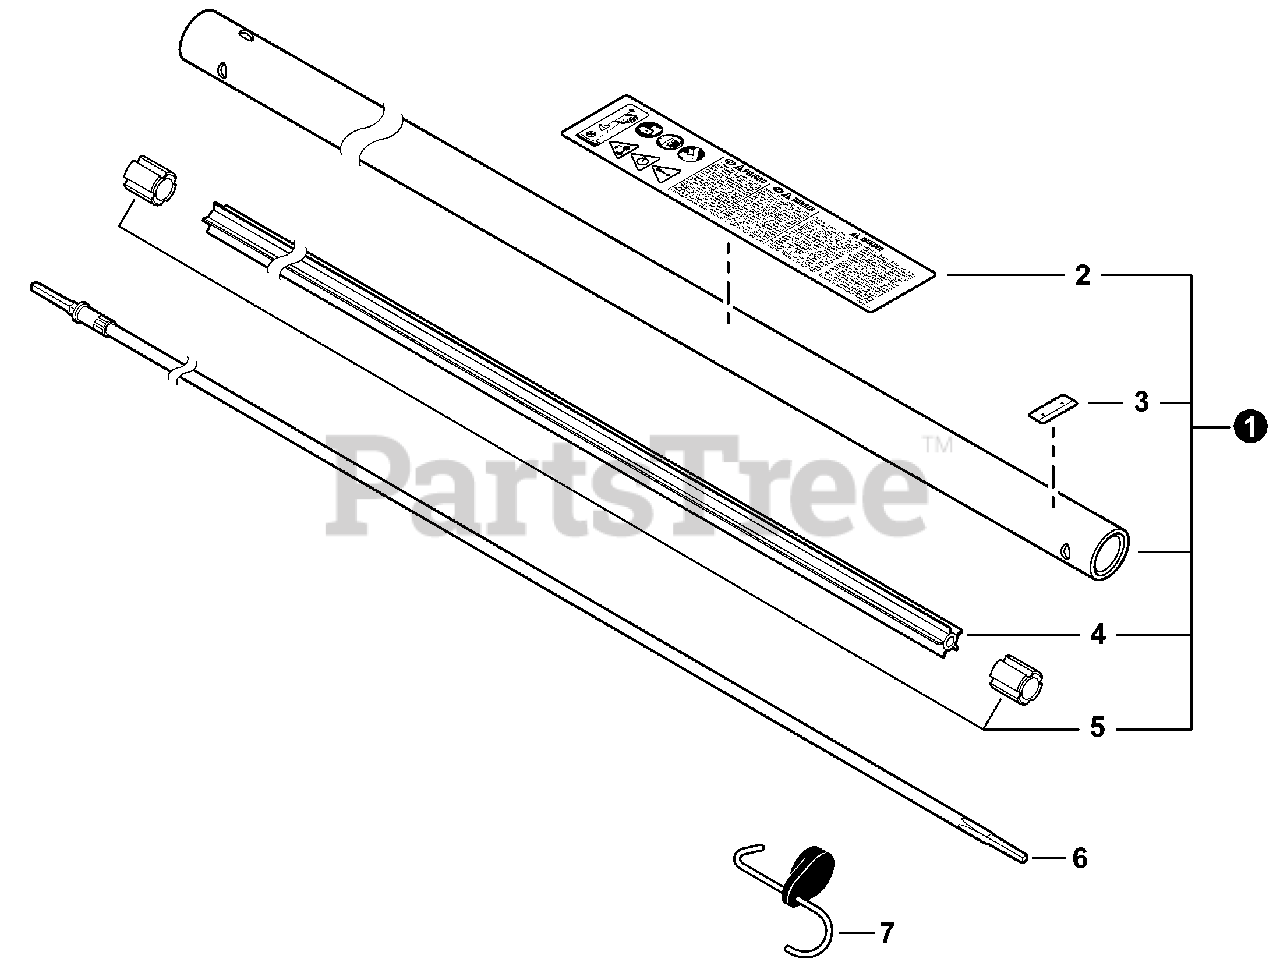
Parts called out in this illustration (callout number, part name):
1	PIPE, MAIN
2	LABEL, CAUTION
3	LABEL - ALIGNMENT
4	LINER - FLEXIBLE
6	DRIVESHAFT - FLEXIBLE
7	HANGER, ATTACHMENT
